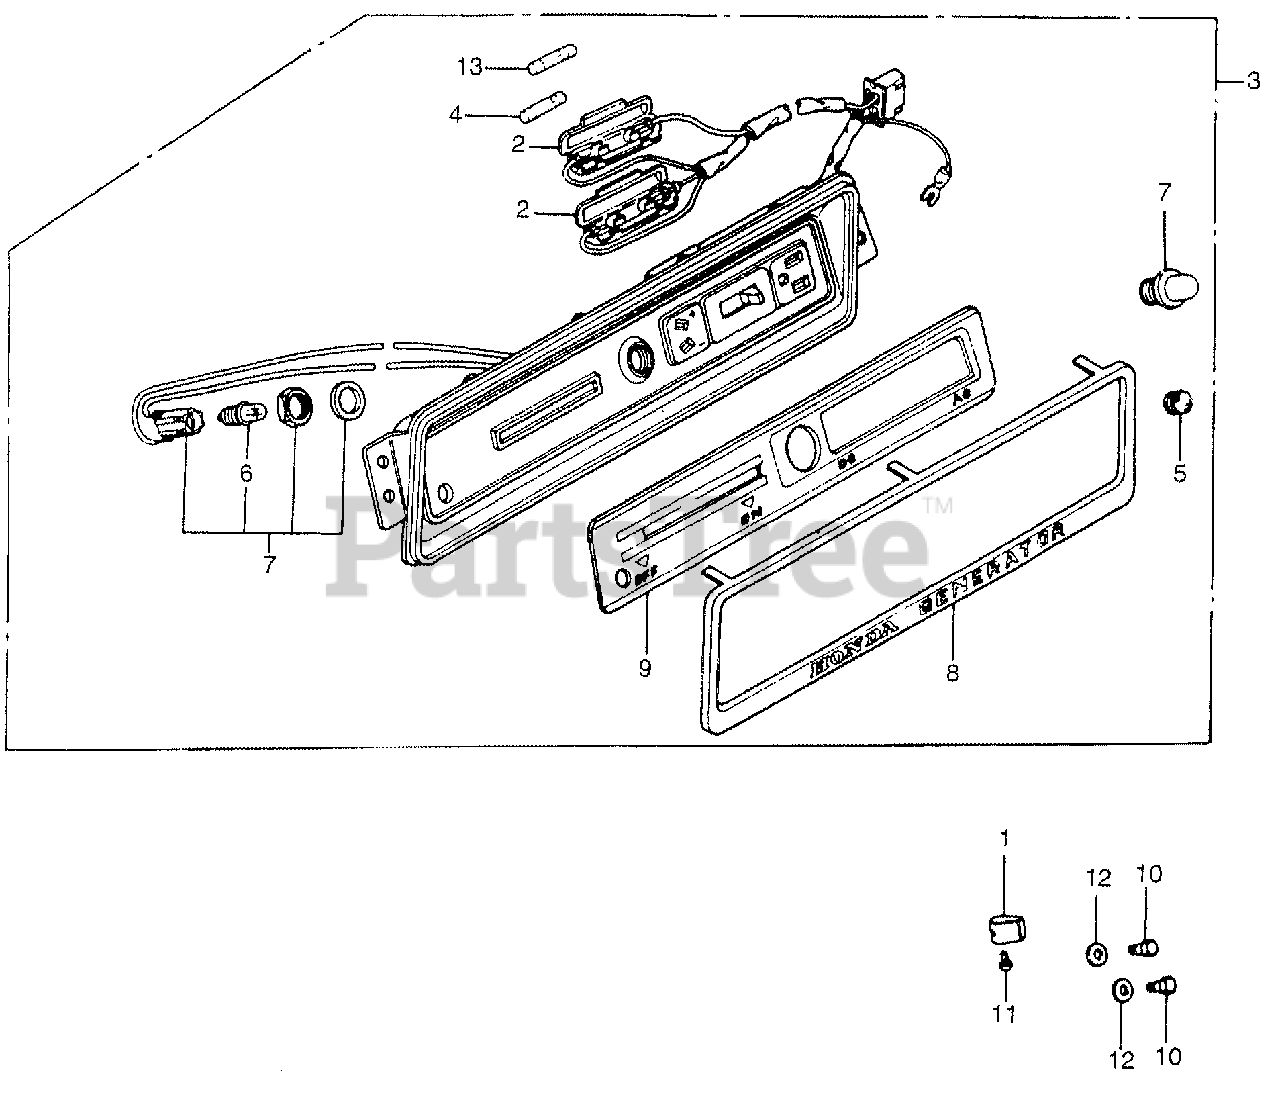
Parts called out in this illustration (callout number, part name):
1	KNOB, ON-OFF (NOT AVAILABLE)
2	CASE, FUSE CONNECTOR
3	PANEL, FR. (NOT AVAILABLE)
4	FUSE ASSY., SPARE
5	GROMMET, CONTROL
6	BULB, DASH (24V-2W)
7	SOCKET ASSY., PILOT LAMP (NOT AVAILABLE)
8	MOLDING, FR. PANEL
9	PLATE, FR. PANEL
10	BOLT, FAN COVER (NOT AVAILABLE)
11	SCREW, PAN (3X6)
12	WASHER, PLAIN (5MM)
13	FUSE A (10A)
